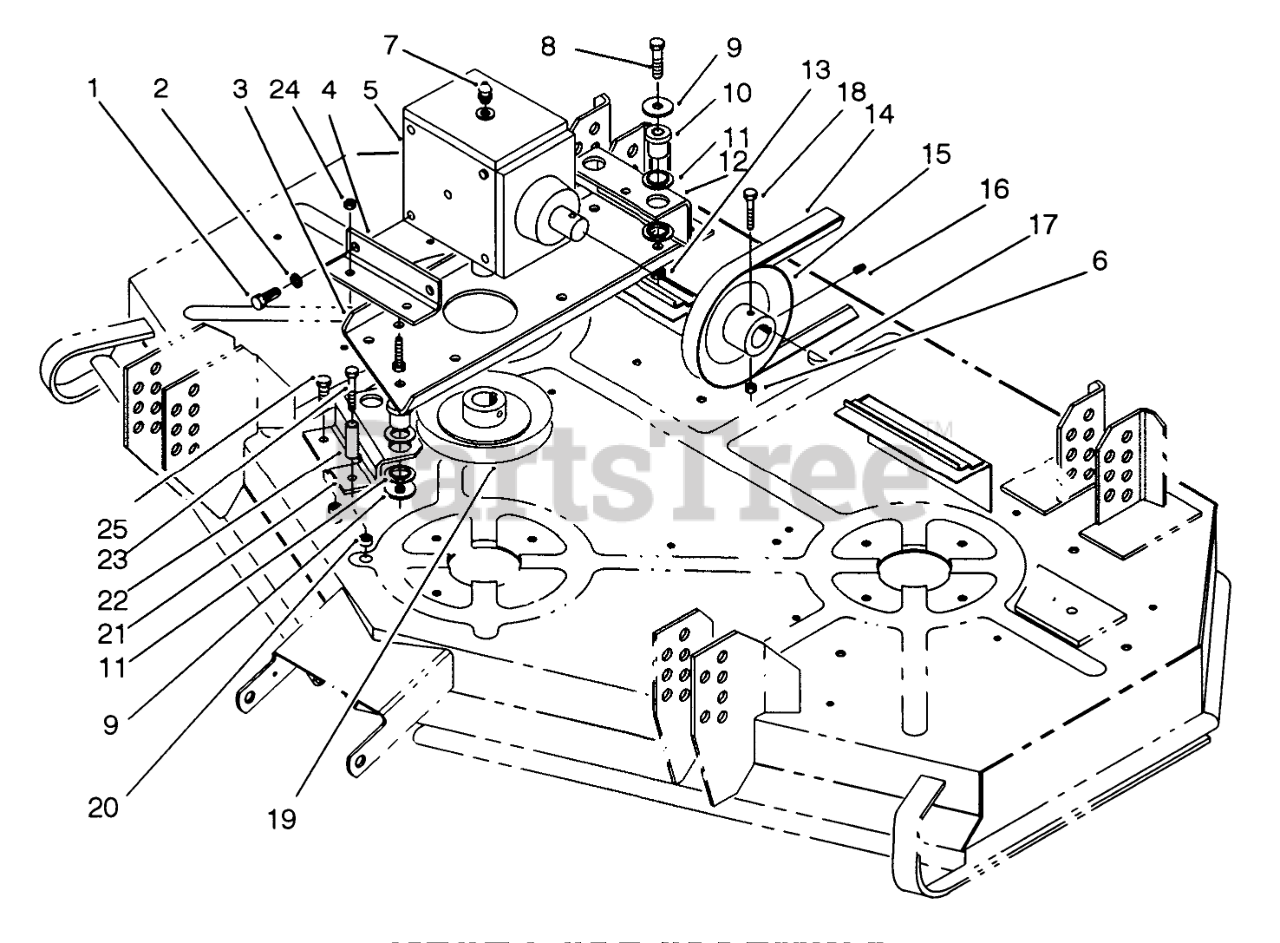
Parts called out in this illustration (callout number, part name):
1	SCREW-HH
2	WASHER-LOCK
3	PLATE - MTG GEAR BOX R
4	ANGLE - GEAR BOX MTG R
5	Gear Box
6	NUT-LOCK, NI
7	FITTING-LUBE
8	SCREW-HH
9	WASHER
10	MOUNT
11	INSERT
12	PLATE BRACKET R
13	NUT-LOCK, NI
14	V-BELT
15	PULLEY - INPUT
16	SCREW-SQH
18	SCREW-HH
19	PULLEY
20	INSERT-THREADED
21	PLATE BRACKET R
22	OUTER TUBE SPACER
23	SCREW-HH
24	NUT-LOCK, NI
25	SCREW-HH
